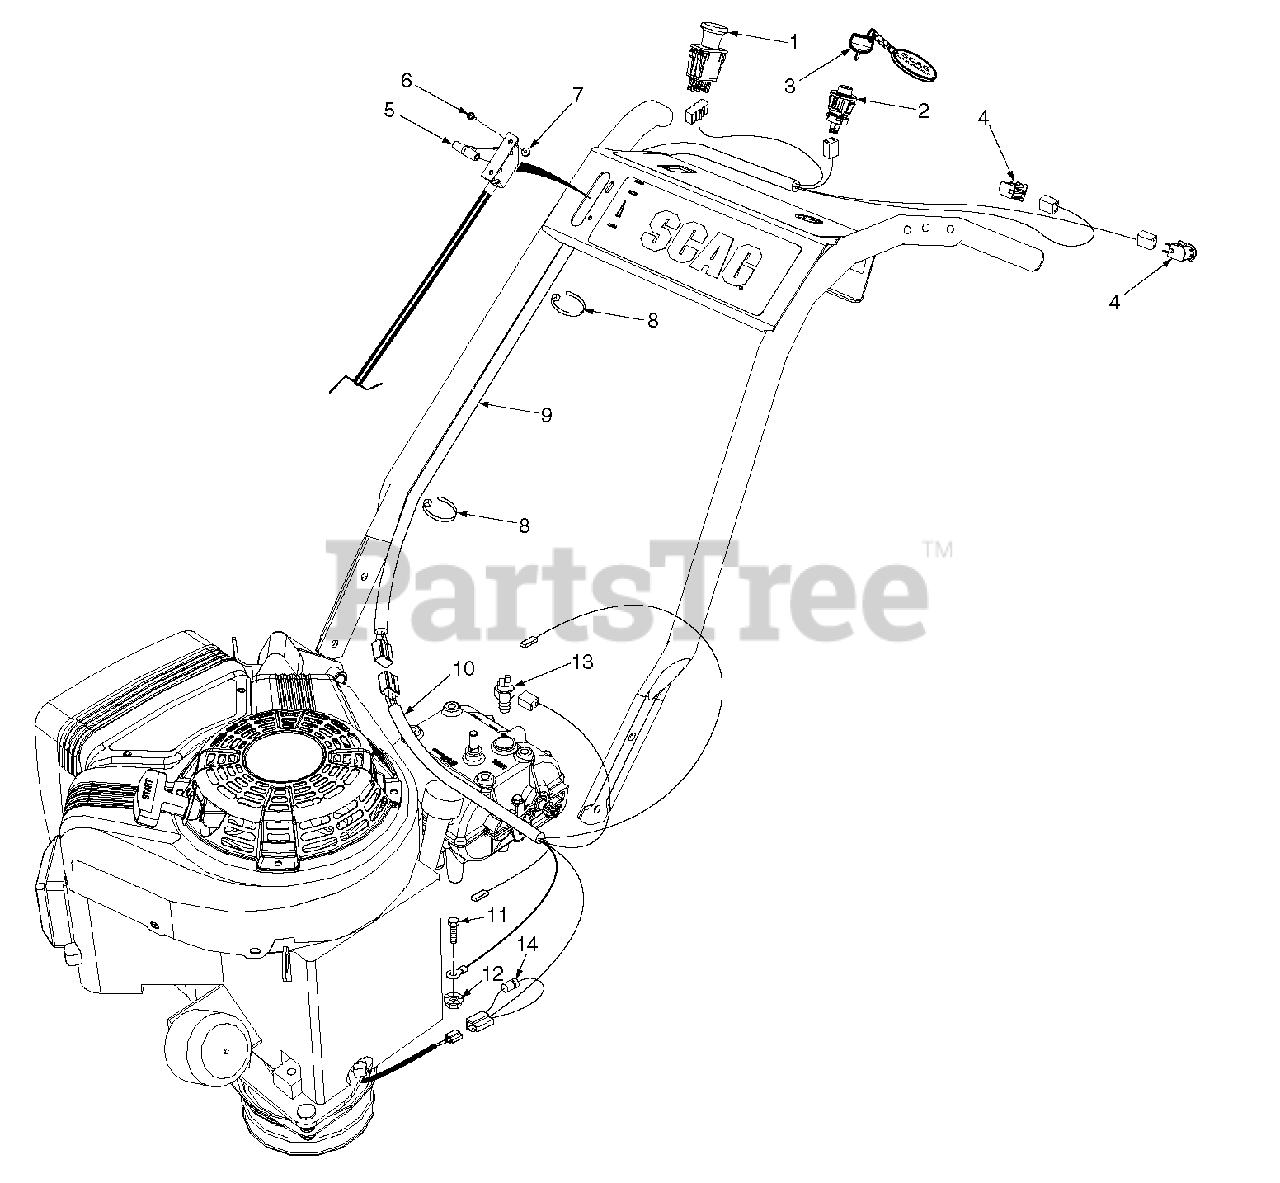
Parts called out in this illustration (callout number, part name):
1	Switch, PTO 10 Amp
2	Keyswitch
3	Key Chain w/Keys
4	Switch
5	Throttle Cable
6	Screw, #10-32 x 1/2"
7	Nut, #10-32
8	Cable Tie
9	Wire Harness, Handle Bar
10	Wire Harness, Engine Deck
11	Bolt, Serrated Flange 5/16-18 x 1-1/2"
12	Nut, Serrated Flange 5/16-18
